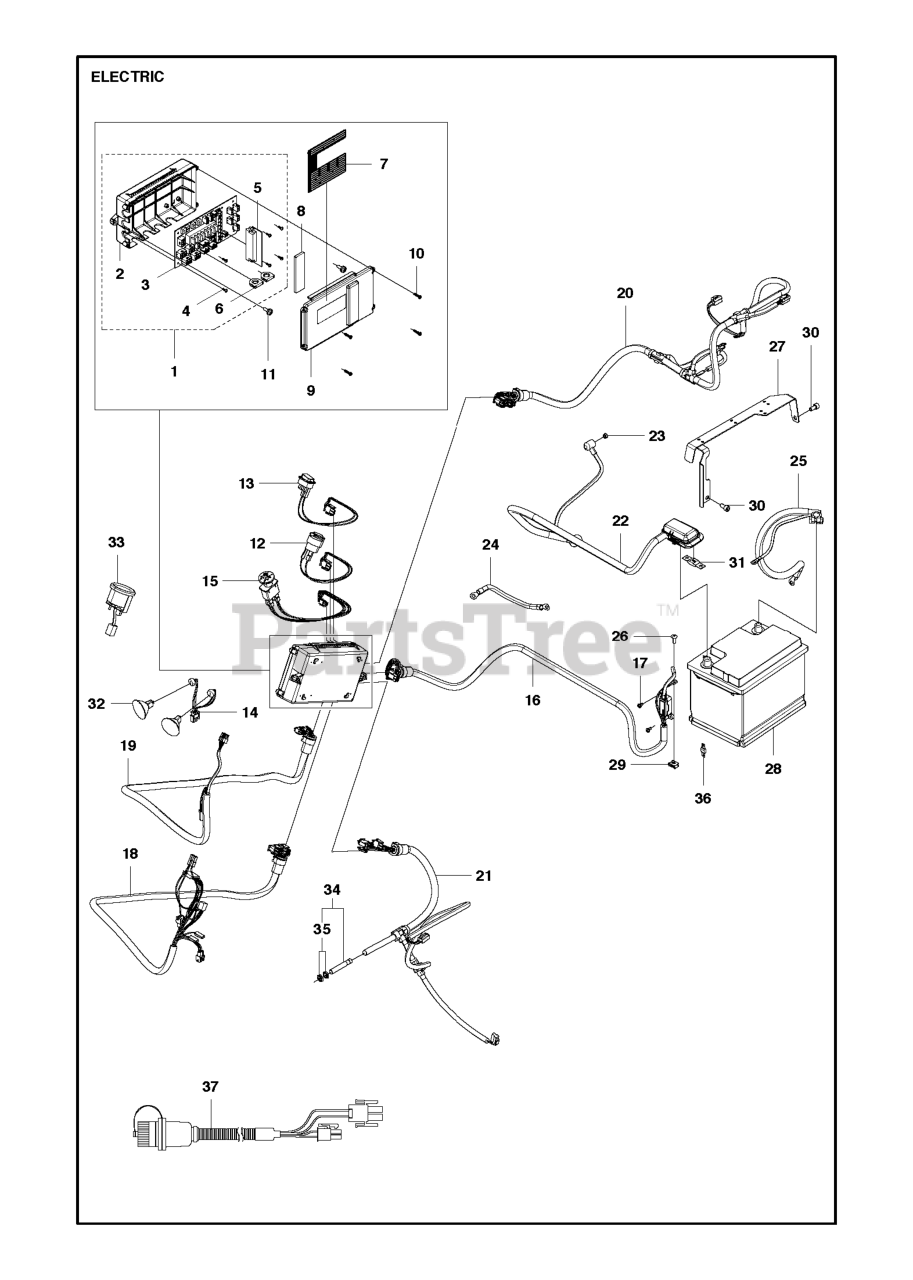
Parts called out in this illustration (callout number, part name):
23	LOCKNUT M6
32	LAMP
36	FUSE 50A
